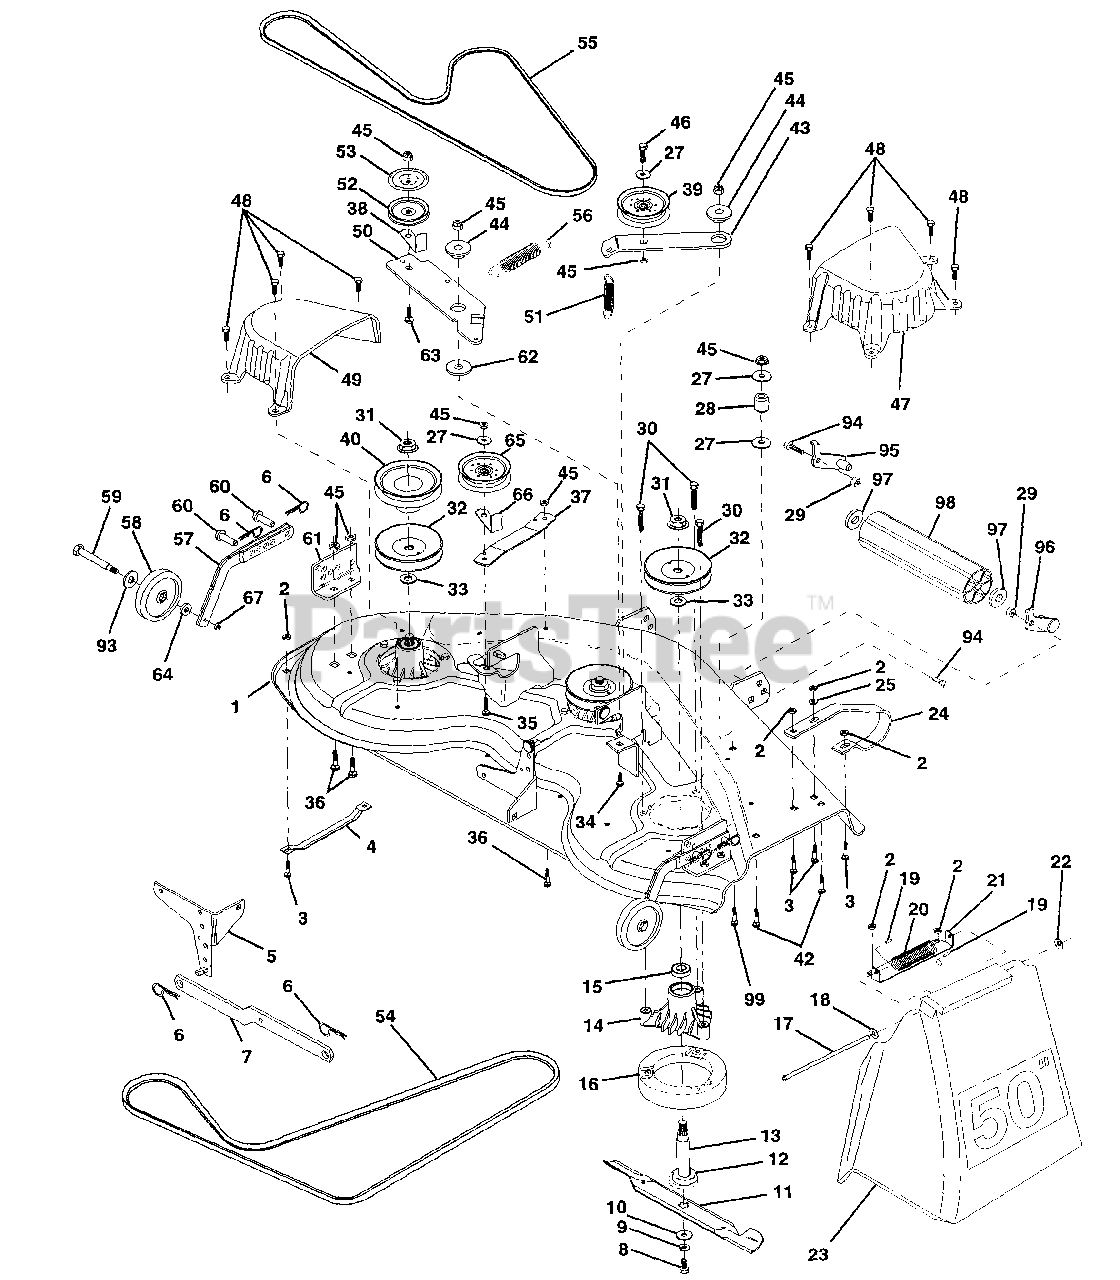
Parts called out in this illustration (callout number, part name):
1	Deck Asm., Mower 50" Vented
2	Locknut, Hex W/Ins 5/16-18 Unc
3	Bolt, Carriage 5/16-18 x 3/4
4	Runner, Mower LH
5	Bracket Asm., Sway Bar
6	Retainer, Spring
7	Arm Suspension, Rear
8	Bolt 3/8-24 x 1.25 Gr. 8 Patched
9	Washer, Lock Hvy 3/8 Unplated
10	Washer, Hard Blade Mower Vented
11	Blade (3 Required)
12	Bearing, Ball #6204 (Mandrel)
13	Shaft Asm., W/Lower Brg
14	Housing, Mandrel 50" Vent
15	Bearing, Ball Mandrel
16	Stripper, Mower Vented
17	Rod, Hinge
18	Washer 11/32 x 5/8 x 16 Ga.
19	Cap, Sleeve
20	Spring, Torsion Deflector
21	Bracket, Deflector
23	Shield, Deflector Mower
24	Runner, RH
25	Washer 11/32 x 3/4 x 16 Ga.
26	Bolt, Carriage 3/8-16 x 1-3/4 Gr. 5
27	Washer 13/32 x 13/16 x 16 Ga.
28	Spacer, Spring Stop Idler
29	Nut, Lock Hex W/Wsh 3/8-16 Unc
30	Screw Thdrol Hex Head
31	Nut, Flg Top Lock Cntr 9/16
32	Pulley, Mandrel
33	Washer, Spacer Mower Vented
34	Bolt, Carriage 3/8-16 x 1-1/4
35	Bolt, Carriage 3/8-16 x 2
36	Bolt, Carriage 3/8-16 x 1 Gr. 5
37	Stiffener, Arm Idler
38	Keeper, Belt Idler
39	Pulley, idler Flat
40	Pulley, Driven
42	Bolt, Carriage 5/16-18 Unc x 3/4
43	Arm, Idler Secondary
44	Spacer, Retainer
45	Nut, Crownlock 3/8-16 Unc
46	Bolt, Fin Hex 3/8-16 Unc x 1-3/4
47	Cover, Mandrel RH
48	Screw, Thd Roll 1/4-20 x 5/8
49	Cover, Mandrel LH
50	Arm, Idler Primary
51	Spring, Secondary
52	Pulley, Idler V Groove
53	Shield, idler
54	V-Belt, Mower Primary
55	V-Belt, Mower Secondary
56	Spring, Primary
57	Bar Asm., Wheel Gauge
58	Wheel, Gauge
59	Bolt, Shoulder
60	Pin, Clevis
61	Bracket, Wheel Gauge
62	Washer Hardened
63	Bolt Carriage 3/8-16 x 1-1/2
64	Washer 3/8 x 7/8 x 14 Ga.
65	Pulley Idler Flat Mower
66	Keeper, Belt Idler 50" Vent
67	Nut, Center Lock 3/8-16
95	Bracket, Asm. Noseroller LH
96	Bracket, Asm. Noseroller RH
97	Washer 17/32 x 7/8 x 16 Ga.
98	Roller, Nose
99	Bolt, Fin Hex 3/8-16 x 1
100	Washer 17/32 x 15/16 x 12 Ga.
